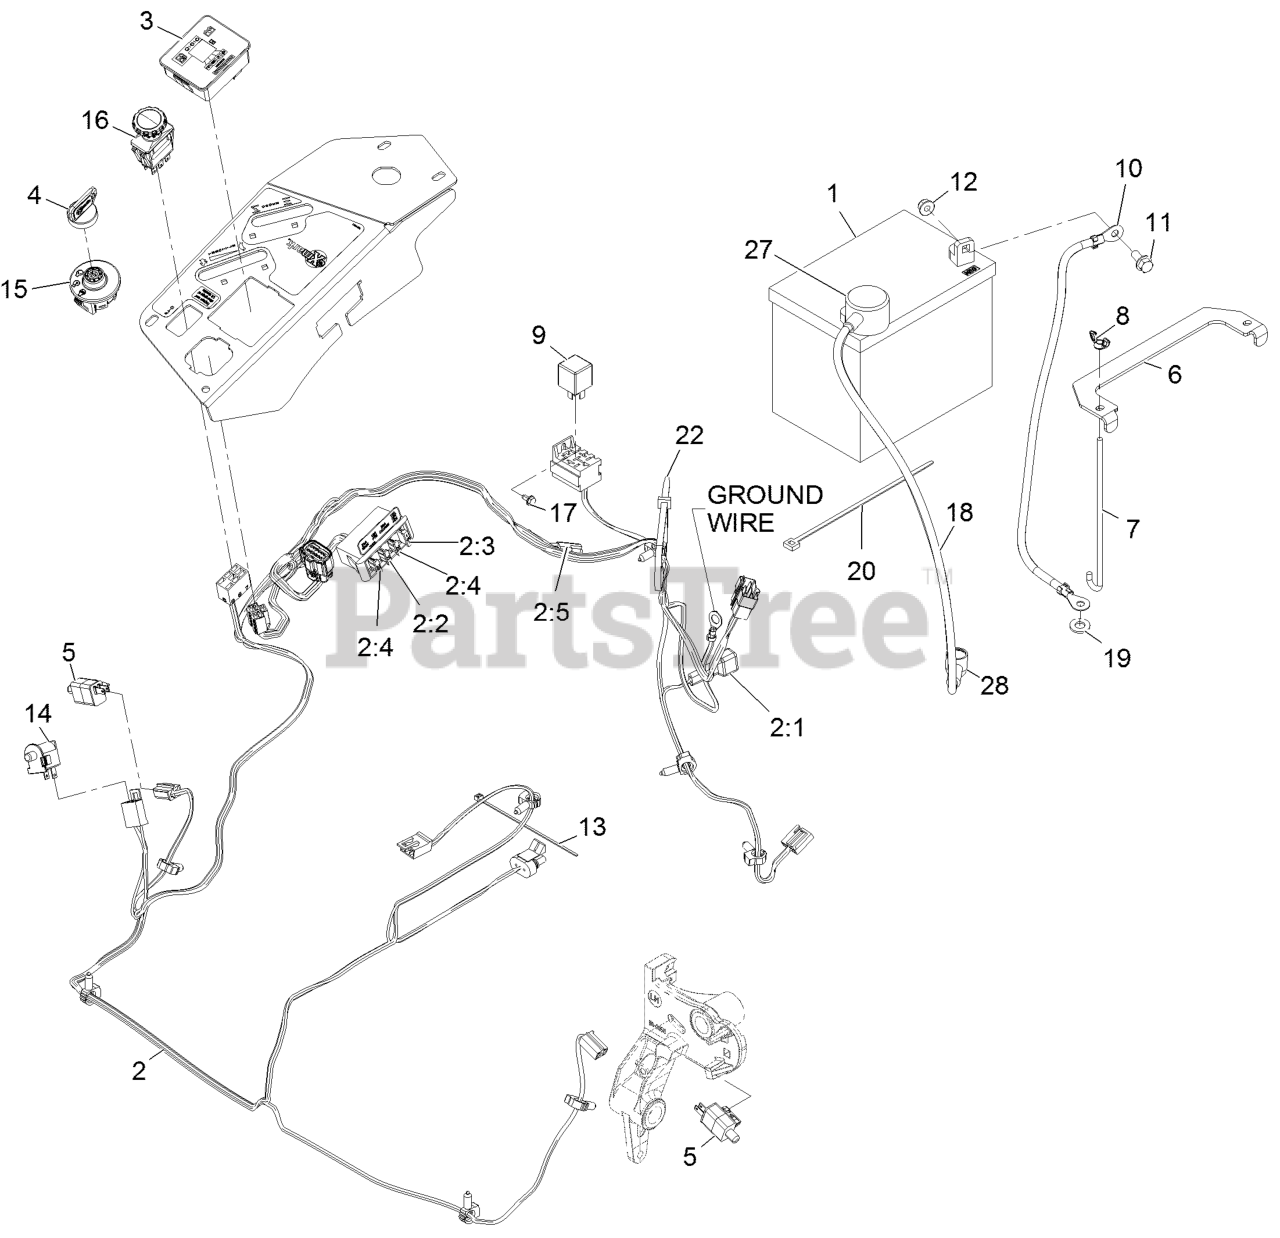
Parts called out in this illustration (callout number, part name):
1	Battery
2	HARNESS-WIRE, MAIN
2:2	FUSE-BLADE, 10 AMP
2:3	FUSE-BLADE, 15 AMP
2:4	FUSE-BLADE, 25 AMP
2:5	CAP-PLUG
3	FUEL/HOUR METER ASM
4	KEYS-IGNITION (SPARE PAIR
4	KEY-IGNITION
6	STRAP-TIE DOWN, BATTERY
7	BOLT-HOLDDOWN
8	WINGNUT
10	CABLE-BATTERY, NEGATIVE
11	SCREW-HHF
12	NUT-HF, NI
13	TIE-CABLE
14	SWITCH-BAIL
16	SWITCH-PTO, 10 AMP
17	SCREW-HWH
18	CABLE-BATTERY, POSITIVE
19	WASHER-FLAT
20	TIE-PLASTIC
22	TIE-PLASTIC
27	INSULATOR-BATTERY
28	INSULATOR-SOLENOID
